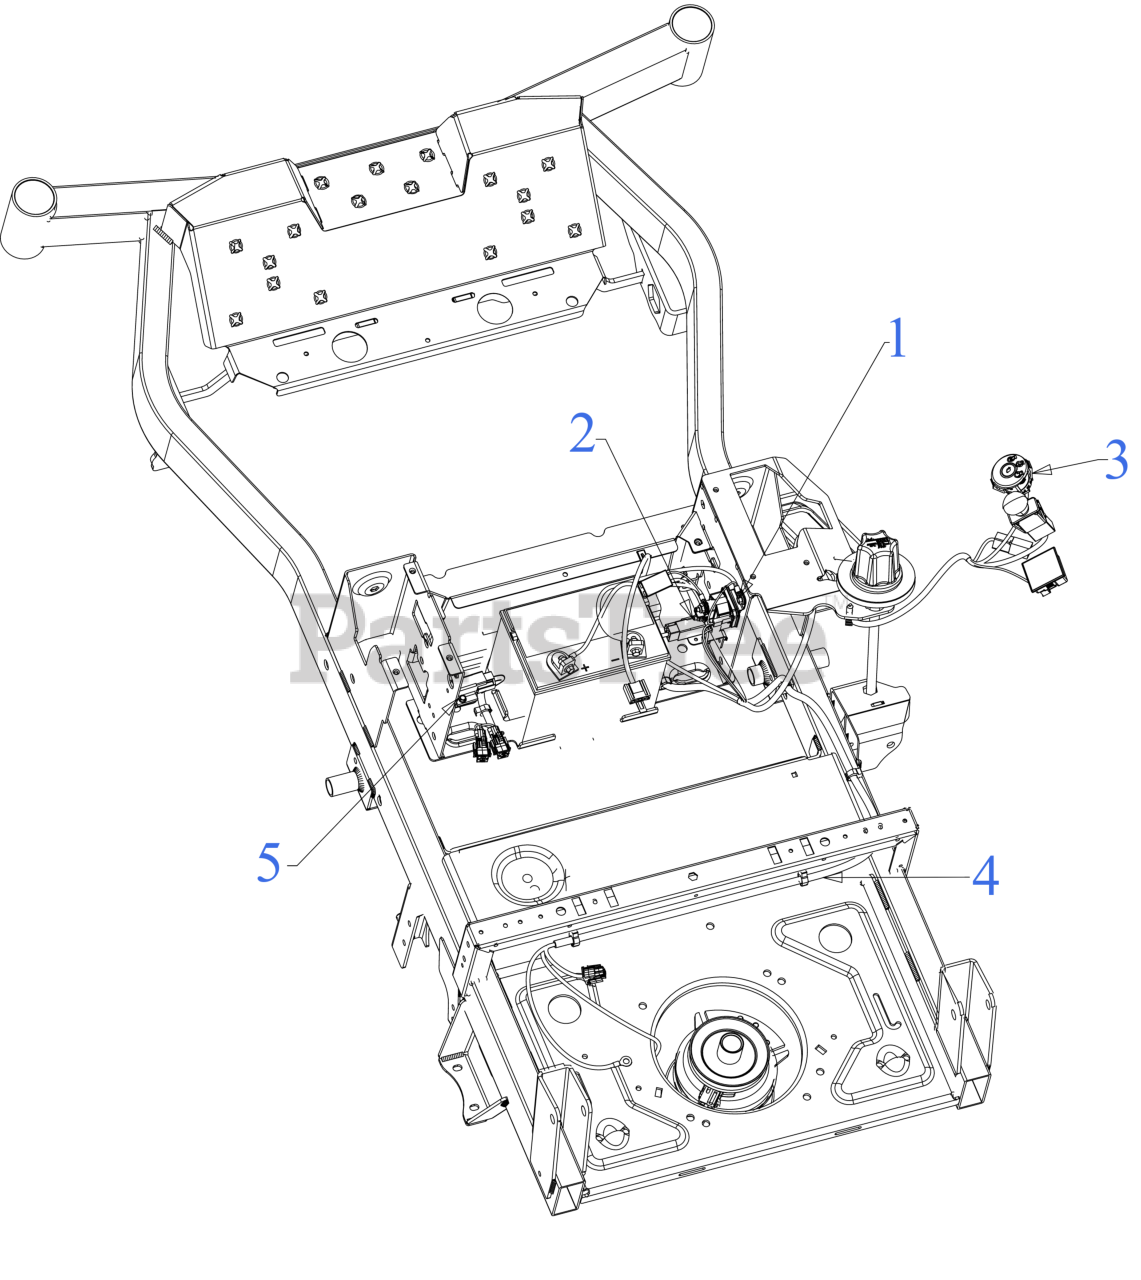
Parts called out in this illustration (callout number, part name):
1	SCREW 1/4-20X.625
2	INTERLOCK SWITCH (NO/NC)
3	KEY SWITCH (3 POS 6 PIN)
4	MAIN HARNESS
5	SHOULDER SCREW
